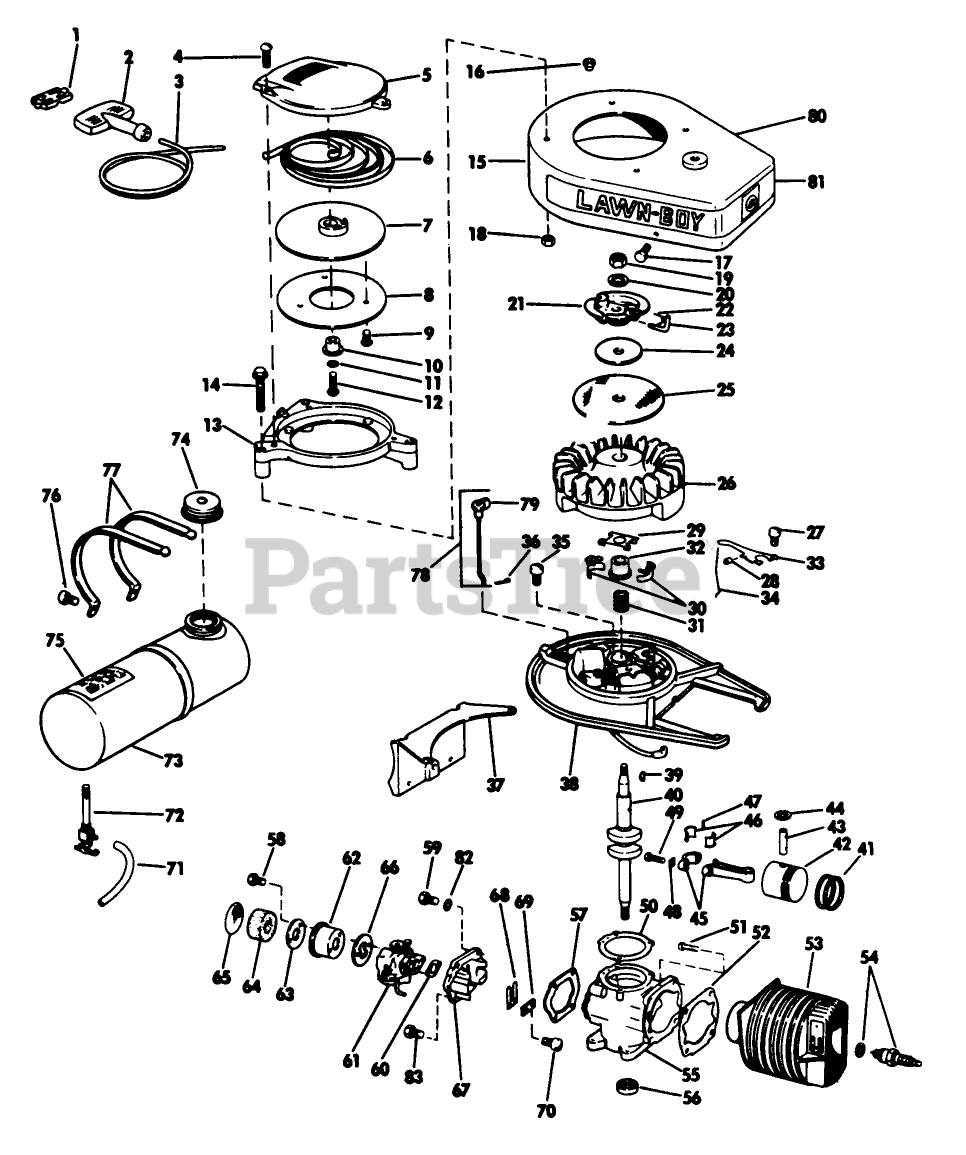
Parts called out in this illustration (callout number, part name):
6	RECOIL SPRING
17	SCREW S
23	PIN - STARTER
28	WEAR BLOCK S
29	COLLAR S
33	GOVERNER LEVER AY
34	GOVERNOR ROD S
35	SCREW S
36	Cotter Pin
44	RING-RETAINING
46	LINER ASM
50	GASKET S
52	GASKET S
59	SCREW S
60	GASKET S
63	BACK-UP PLATE
64	ELEMENT
66	GASKET S
69	PLATE-BACKUP, REED
72	VALVE&SCREEN SM
79	KNOB, CHOKE BAR
83	SCREW S
